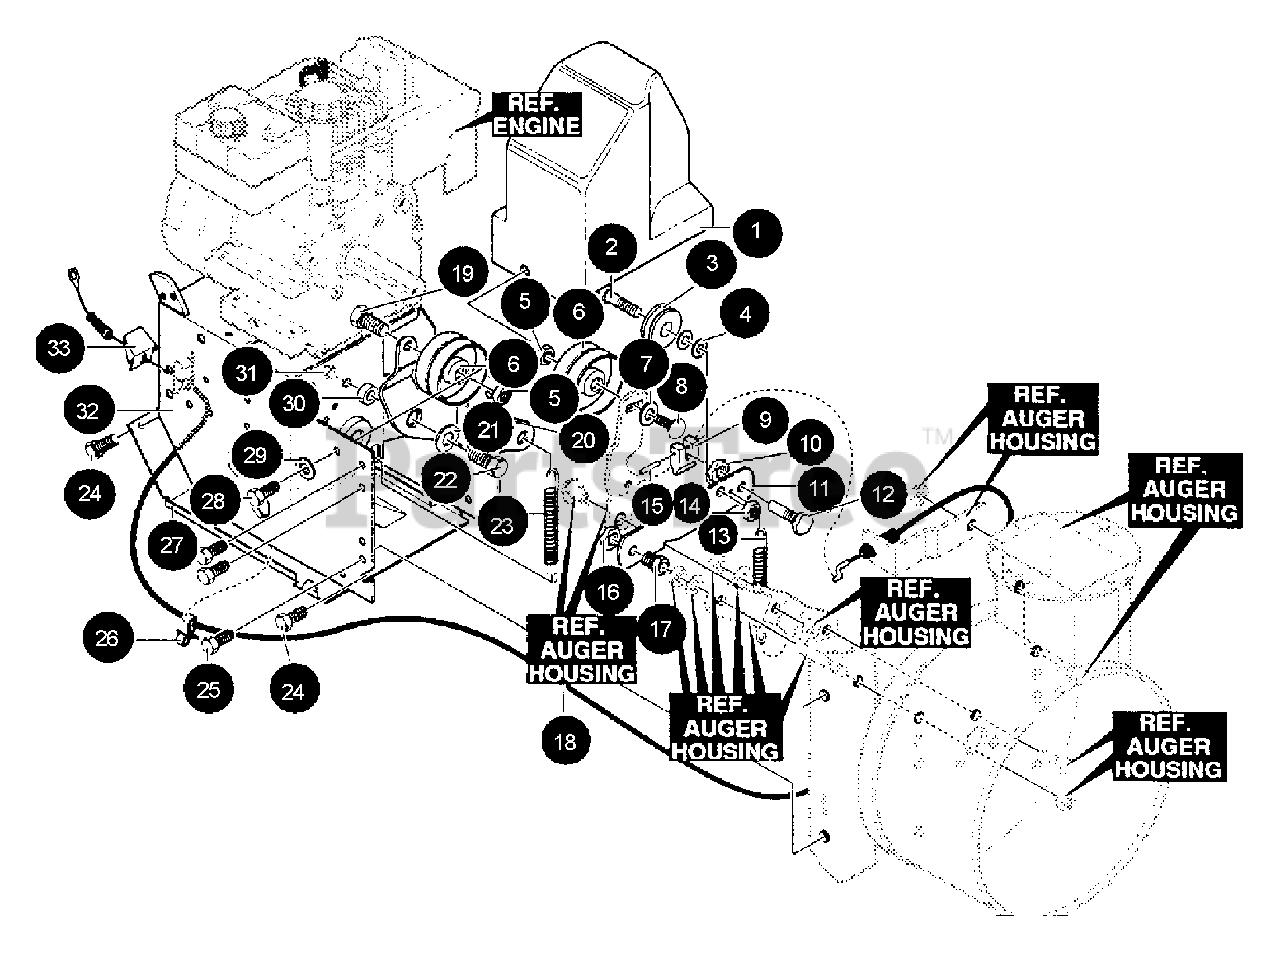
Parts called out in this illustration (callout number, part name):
1	COVER, BELT
2	BOLT - .375X.375 HHSH 1/4-20
3	PULLEY
4	WASHER
5	LOCKNUT - 3/8-16
6	PULLEY, IDLER
7	WASHER - .506 X .75X .024"
8	BOLT, 3/8-16X1.25 CARR
9	PAD, AUGER/IMPELLER BRAKE
10	LOCKNUT - 1/2-20
11	BRACKET
12	BOLT, BRAKE ARM
13	SPRING, IDLER BRAKE
14	NUT - 1/4-20
15	PIN - SPRING
16	NUT - 9/16-18
17	BOLT, BRAKE ARM 9/16-18
18	CABLE, AUGER
19	SCREW - 3/8-16 X 1-1/4"
20	LEVER, IDLER ARM TRACTION
21	WASHER - .328X1.25X.075
22	SCREW - 5/16-18 X 3/4"
23	SPRING, IDLER
24	SCREW - 1/4-20 X .63" -- TAPPING
25	SCREW - 5/16-18 X 1/2"
26	CLIP, CABLE
27	COVER, BOTTOM
28	WASHER
29	BUSHING, IDLER LEVER
30	NUT - 5/16-18
31	FRAME ASSY
32	SHIELD, CABLE GUARD
